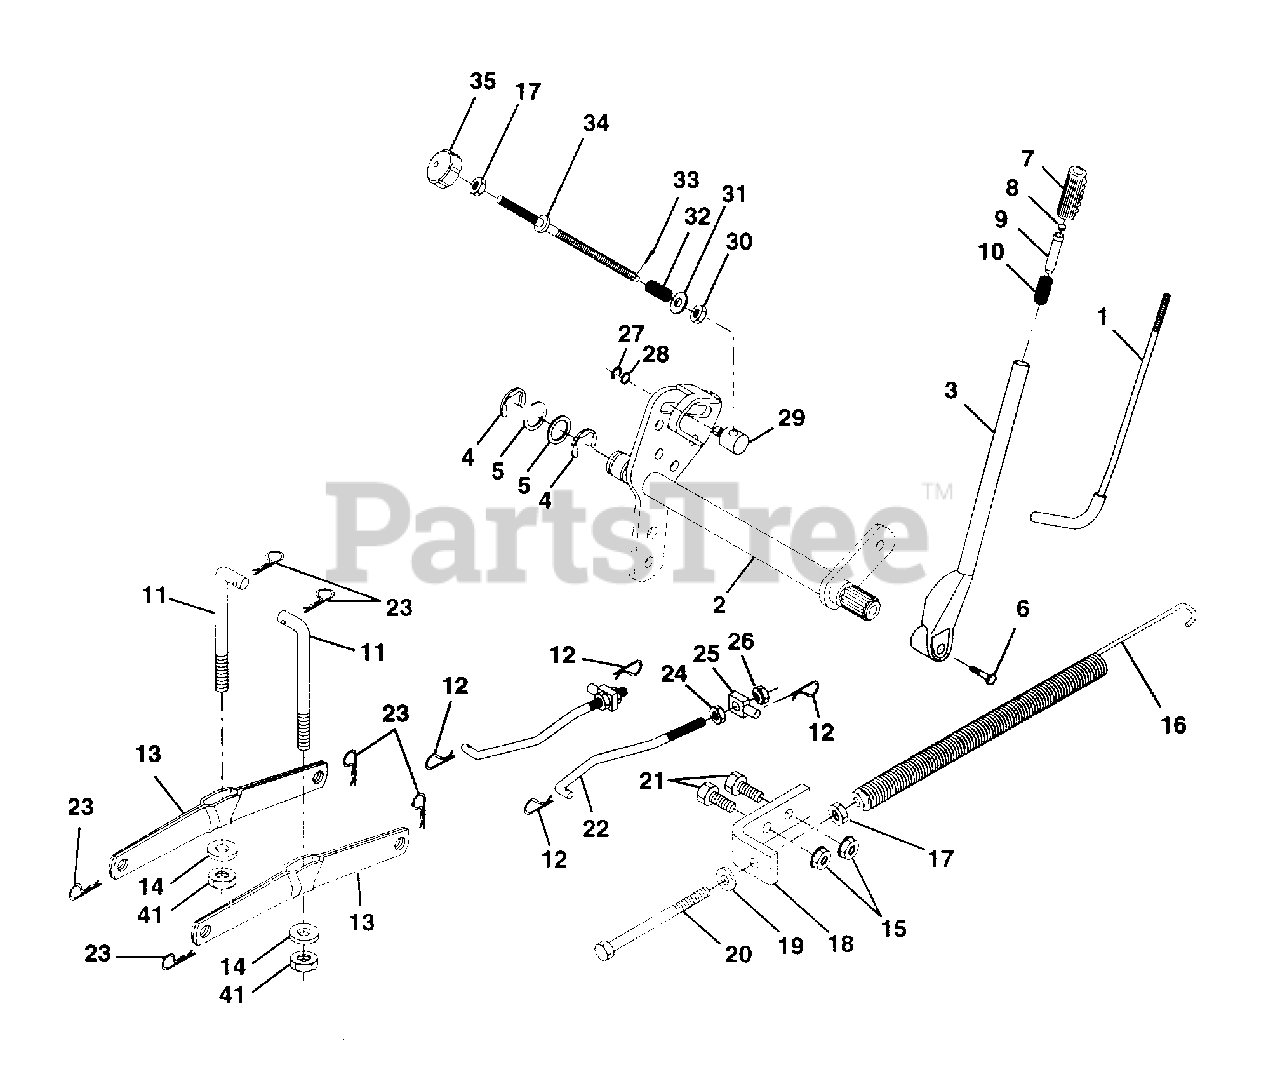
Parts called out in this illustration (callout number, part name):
1	LEVER ROD LT
2	SHAFT.LIFT.VGT.95
4	E-RING
5	WASHER
6	"BOLT,HEX"
7	GRIP
8	BUTTON PLUNGER YELLOW
10	SPRING T
11	LINK.LIFT.MWR.VGT
12	RETAINER.SPRING
13	ARM SUSP REAR
14	BEARING PVT LH
17	NUT
18	BRACKET SPRING AS
19	WASHER
20	BOLT-ADJ SPRING T
21	BOLT
22	LINK.FRONT
24	NUT
25	TRUNION
26	NUT.LK.W/WSH.1/2.
27	KLIP RING
28	WASHER
29	TRUNION LT
30	NUT T
31	WASHER
32	SPRING.COMP.INF.H
34	ROD.ADJ.LIFT
35	KNOB INF 3/8-16
41	NUT.CROWNLOCK.3/8
